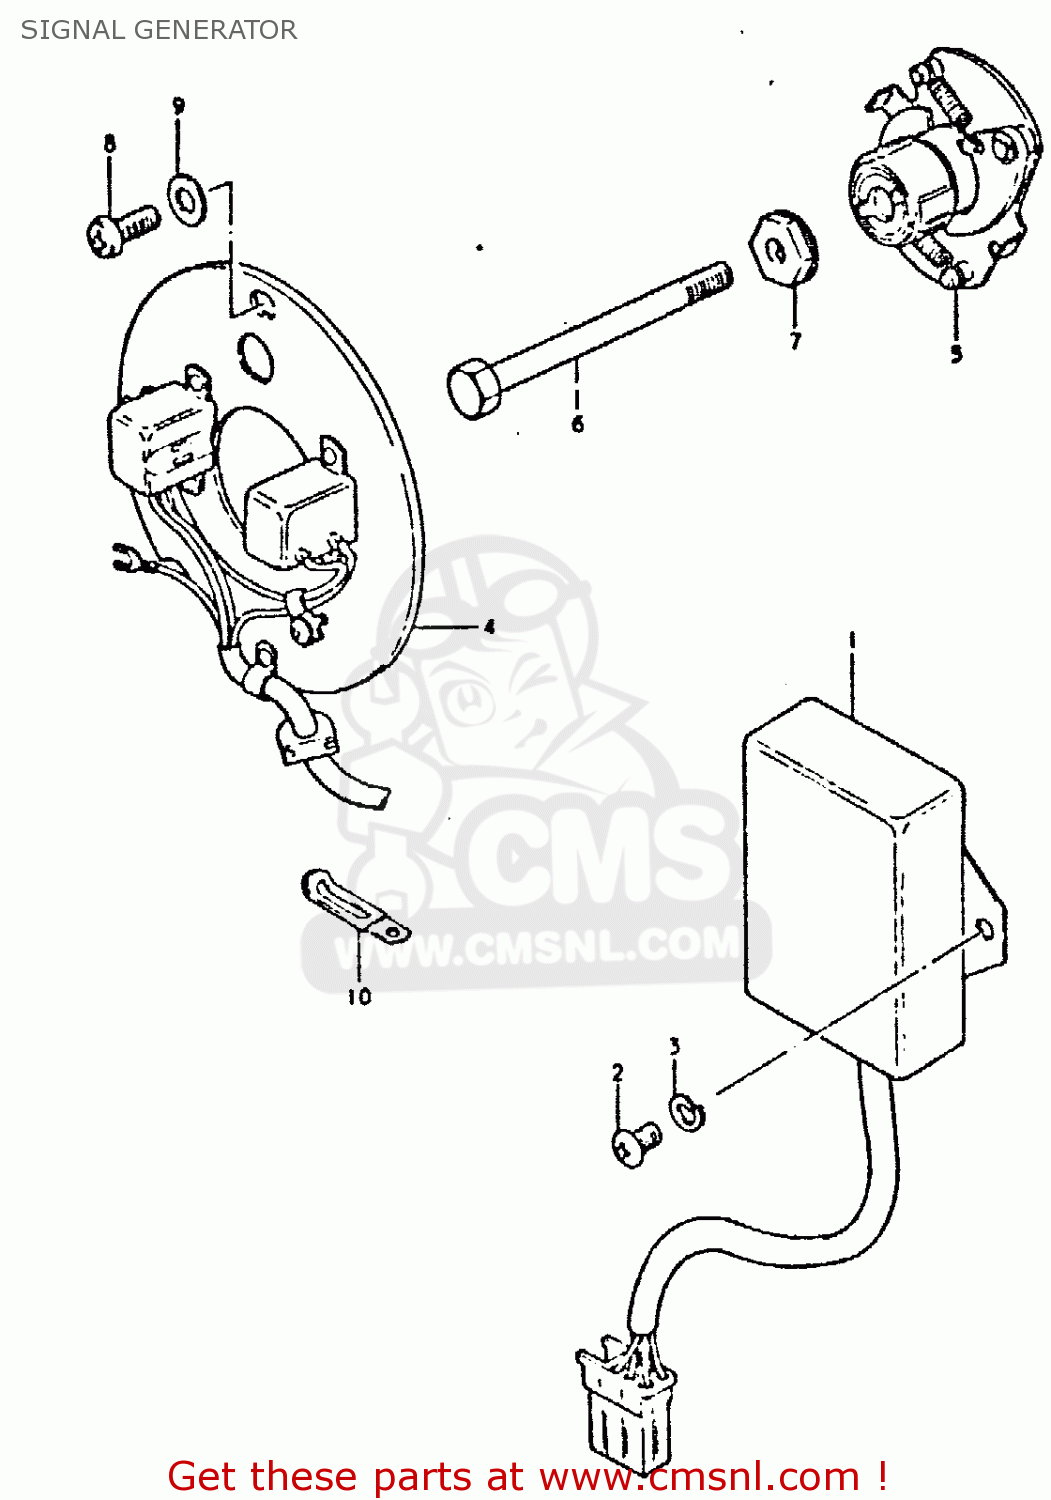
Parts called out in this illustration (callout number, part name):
1	CDI UNIT KOKUSAN
2	SCREW
3	LOCK WASHER
4	SIGNAL GENERATOR ASSEMBLY
5	GOVERNOR ASSEMBLY
6	BOLT 6X60
7	WASHER,CONTACT BREAKER
8	SCREW(5X12)
9	WASHER
10	CLAMP L:35
